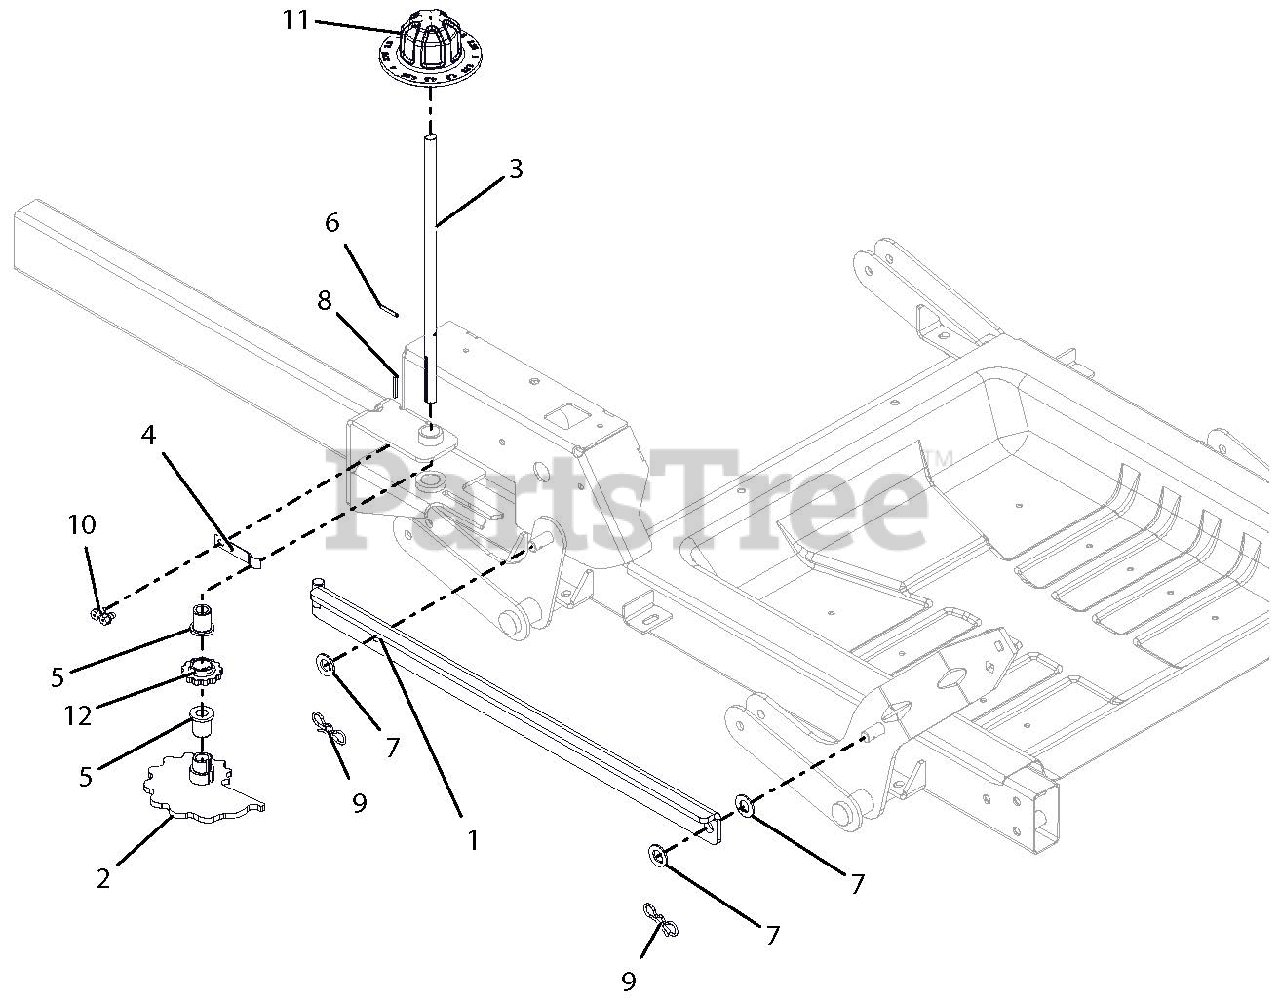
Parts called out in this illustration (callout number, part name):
1	WLDMT, HOC LINK
2	WLDMT, HOC CAM
3	SHAFT, HOC CAM
4	ARM, HOC DETENT
5	BSHG-FLG, .503X.750X.875X1.00
6	PIN-ROLL .125X1.00
7	WSHR-FL-NYL .518X1.000X.080
8	KEY, 1/8 X 1/8 X 1.0
9	PIN,BOW TIE LOCKING .091X1.875
10	@SCR-TAP .25-20X.37 HWH YWZ TR
11	KNOB, HOC
12	GEAR, HOC INDEX
